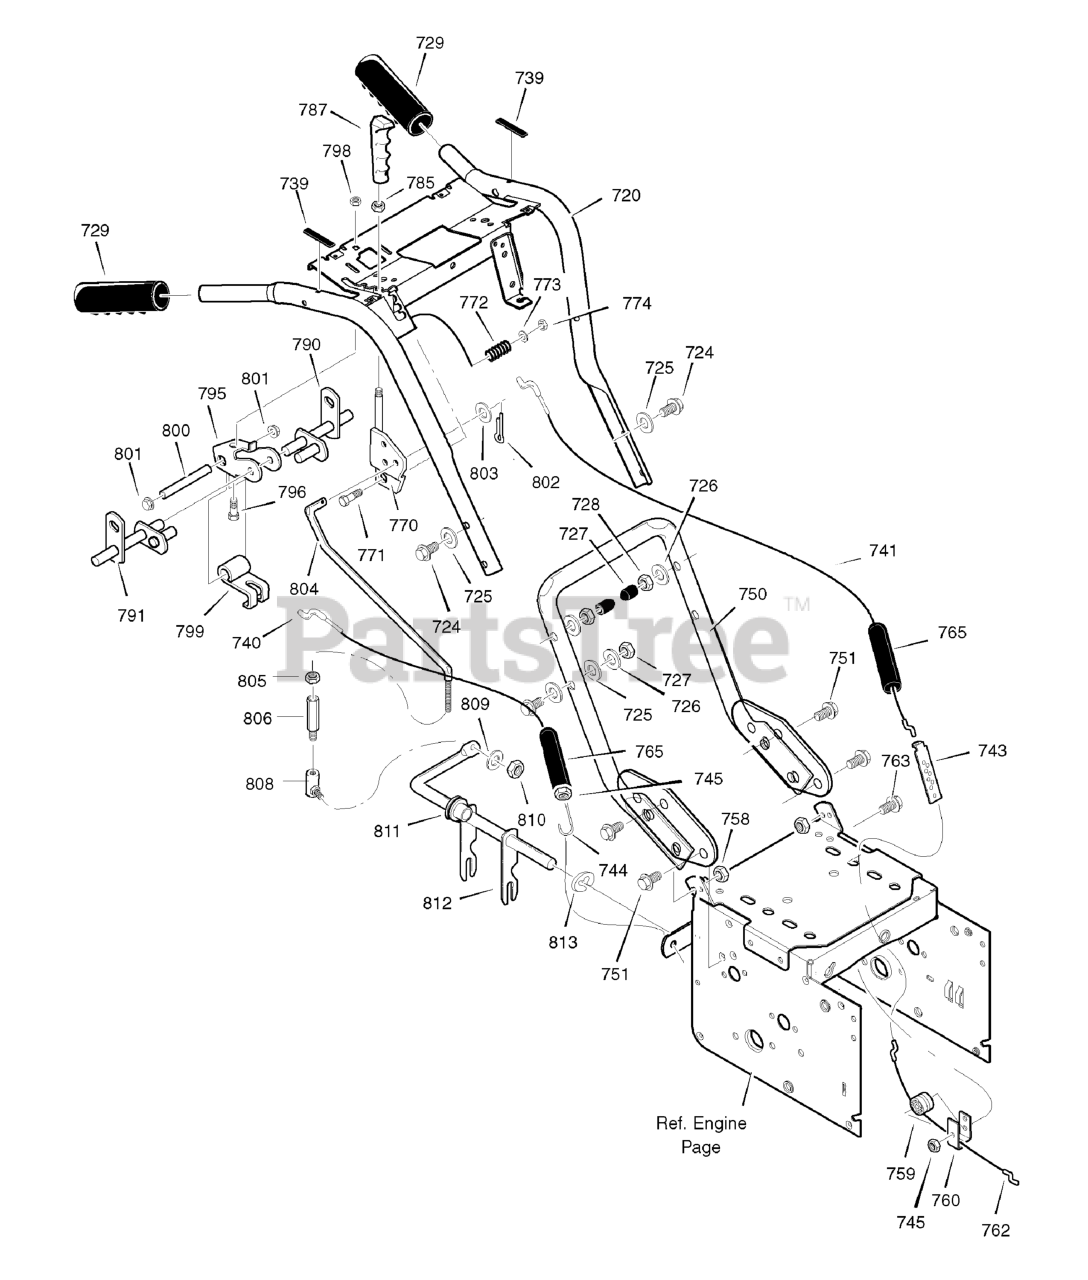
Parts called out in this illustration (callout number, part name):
720	HANDLE ASSEMBLY
724	SCREW
725	WASHER, Flat, 13/32
726	WASHER
727	NUT
728	STOP, PLASTIC
729	GRIP, HANDLE
739	BUMPER
740	CABLE, AUGER CLUTCH
741	CABLE, DRIVE
743	BRACKET, CABLE ADJUST
744	SPRING, CLUTCH
745	NUT, HEX
750	HANDLE, LOWER
751	SCREW
758	NUT, HEX 5/16-18
759	SPOOL, CABLE
760	BRACKET, SPOOL
762	CABLE, LOWER DRIVE
763	BOLT, HEX 1/4-20 X 1.5
765	BOOT, CABLE
770	BRACKET, SHIFT
771	SCREW
773	WASHER, Flat, 13/32
774	NUT, HEX
785	NUT, HEX
787	KNOB, SHIFT
790	ROD, ASSEMBLY LH
791	ROD, ASSEMBLY RH
795	BRACKET, CAM
796	SCREW
798	NUT, NYLOCK
799	CAM LOCK
800	PIN, SPRING PIVOT
801	NUT, PUSH ON
802	PIN, COTTER
803	FLATWASHER
804	ROD, SPEED CONTROL
805	NUT, 5/16-18
806	ADAPTER, ROD
808	BALLJOINT, STEEL
809	WASHER
810	NUT, 5/16-18
811	BEARING, FLANGE
812	ROD, YOKE
813	RETAINER, RING
